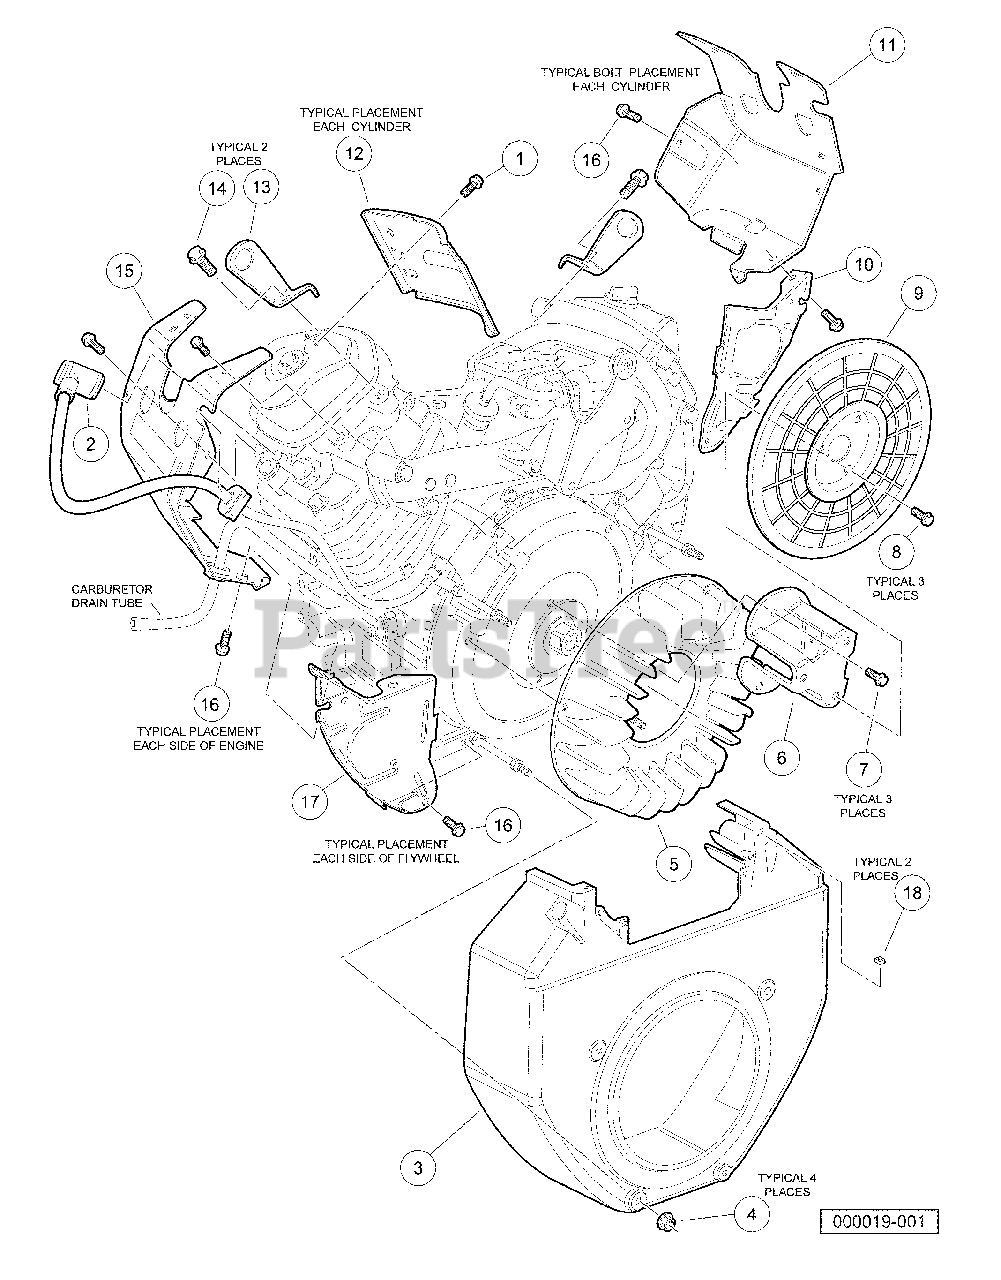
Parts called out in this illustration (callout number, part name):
1	Bolt, Flange Head, M6 X 11 X 4
2	Cap Assy, Noise Suppressor
3	Cover, Fan, Bright Red
4	Nut, Flange, M6
5	Fan, Cooling
6	Holder, Screen Grid
7	Bolt, Flange Head, M8 X 1.25 X 16
8	Bolt, Flange Head, M6 X 1 X 12
9	Grid Screen, PTO
10	Plate, R Side
12	Shroud, Head
13	Hanger, Engine
14	Bolt, Flange Head, M8 X 1.25 X 20
16	Bolt, Flange Head, M6 X 1 X 12
17	Plate, Left Side
18	Nut, Square, 5mm
